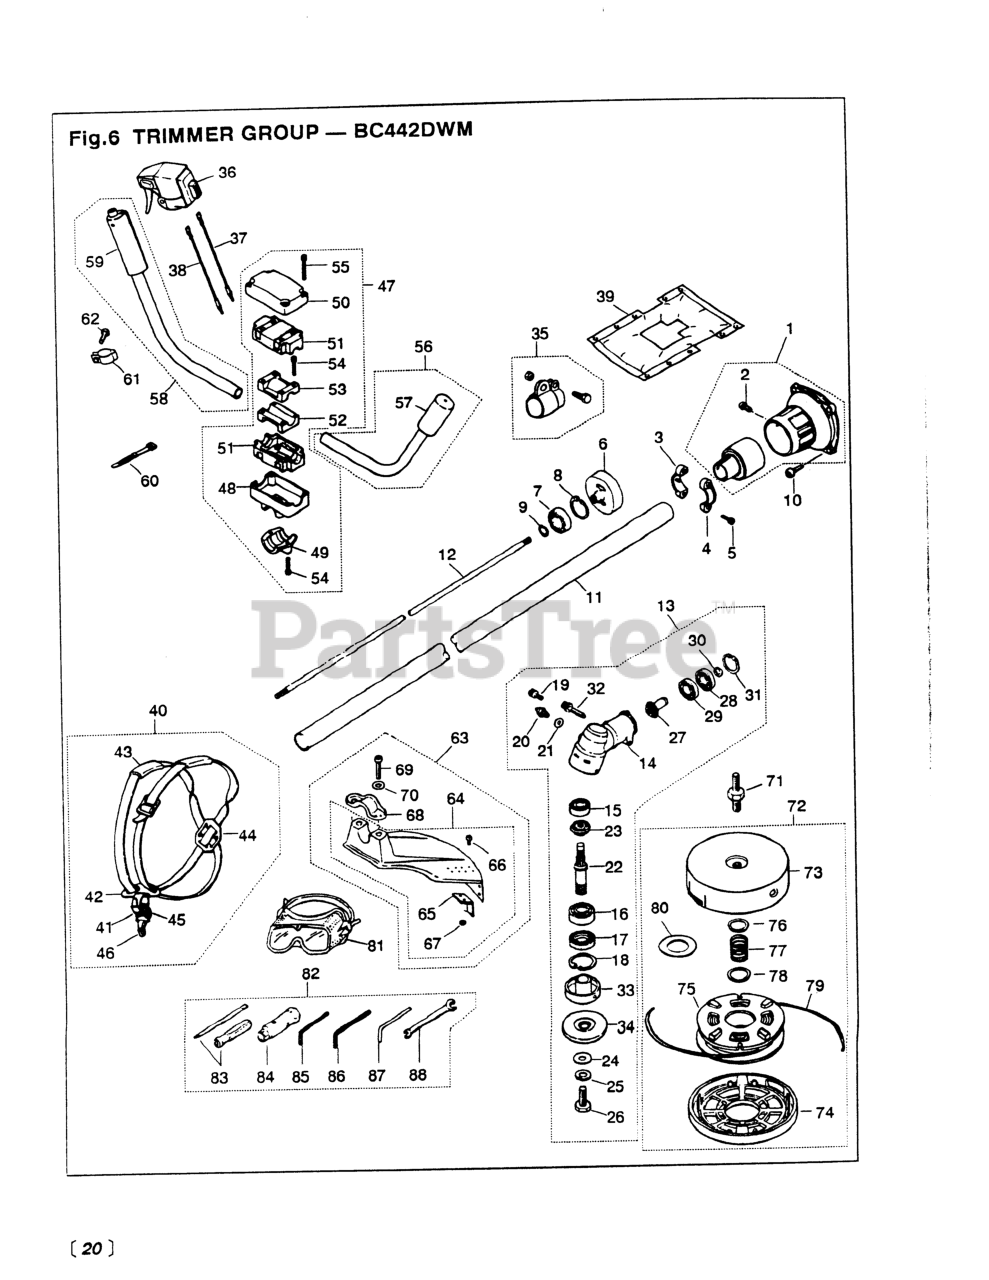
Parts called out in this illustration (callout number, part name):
1	HOUSING COMPLETE
2	SCREW, M6 x 10
4	CLAMP (B)
5	BOLT
6	DRUM, SPLINED
7	BEARING
8	RING, SNAP, M35 X 1.5
9	RING, SNAP, M15 X 1.0
10	BOLT, M6 X 20
12	SHAFT (USE 6340-12211)
13	GEARCASE ASSY (RPLS -13001)
14	GEARCASE (RPLS -13113)
15	BEARING (RPLS T3403-13510)
18	RING, SNAP, M35 X 1.5
19	BOLT, M5 X 10
20	FITTING, GREASE
21	WASHER, M6 X .8
22	SHAFT (RPLS -13211)
24	WASHER, M10 x 3.2
25	WASHER
26	BOLT (REPLACES 3130-13260)
28	BEARING
29	BEARING
31	RING, SNAP, M28 x 1.2
32	BOLT, M6 x 1.35
33	HOLDER (A) (RPLS -13240)
34	HOLDER (B)
35	HANGER COMPLETE
36	LEVER ASSEMBLY
37	CORD A (RED)
38	CORD (RPLS -14720)
43	PROTECTOR
49	CAP, LOWER
50	CAP, UPPER
51	ABSORBER
52	CLAMP (A)
53	CLAMP (B)
54	BOLT, M5 X 25
55	BOLT, M5 X 30
56	HANDLE COMPL, LEFT
58	HANDLE COMPL, RIGHT
59	GRIP
60	BAND
61	CLAMP
62	SCREW, M5 X 16
65	BLADE
66	SCREW, M5 x 12
67	NUT
68	CLAMP
69	BOLT, M6 x 1.30
70	WASHER, M6 X 15
71	ARBOR, 10MM
72	6
74	COVER
76	PLATE, LARGE
78	PLATE, SMALL
79	CORD
80	SPACER
83	SCREWDRIVER
85	WRENCH (TOOL)
86	WRENCH (TOOL)
87	BAR
88	SPANNER, 8 X 10 (RPLS 2540- )
